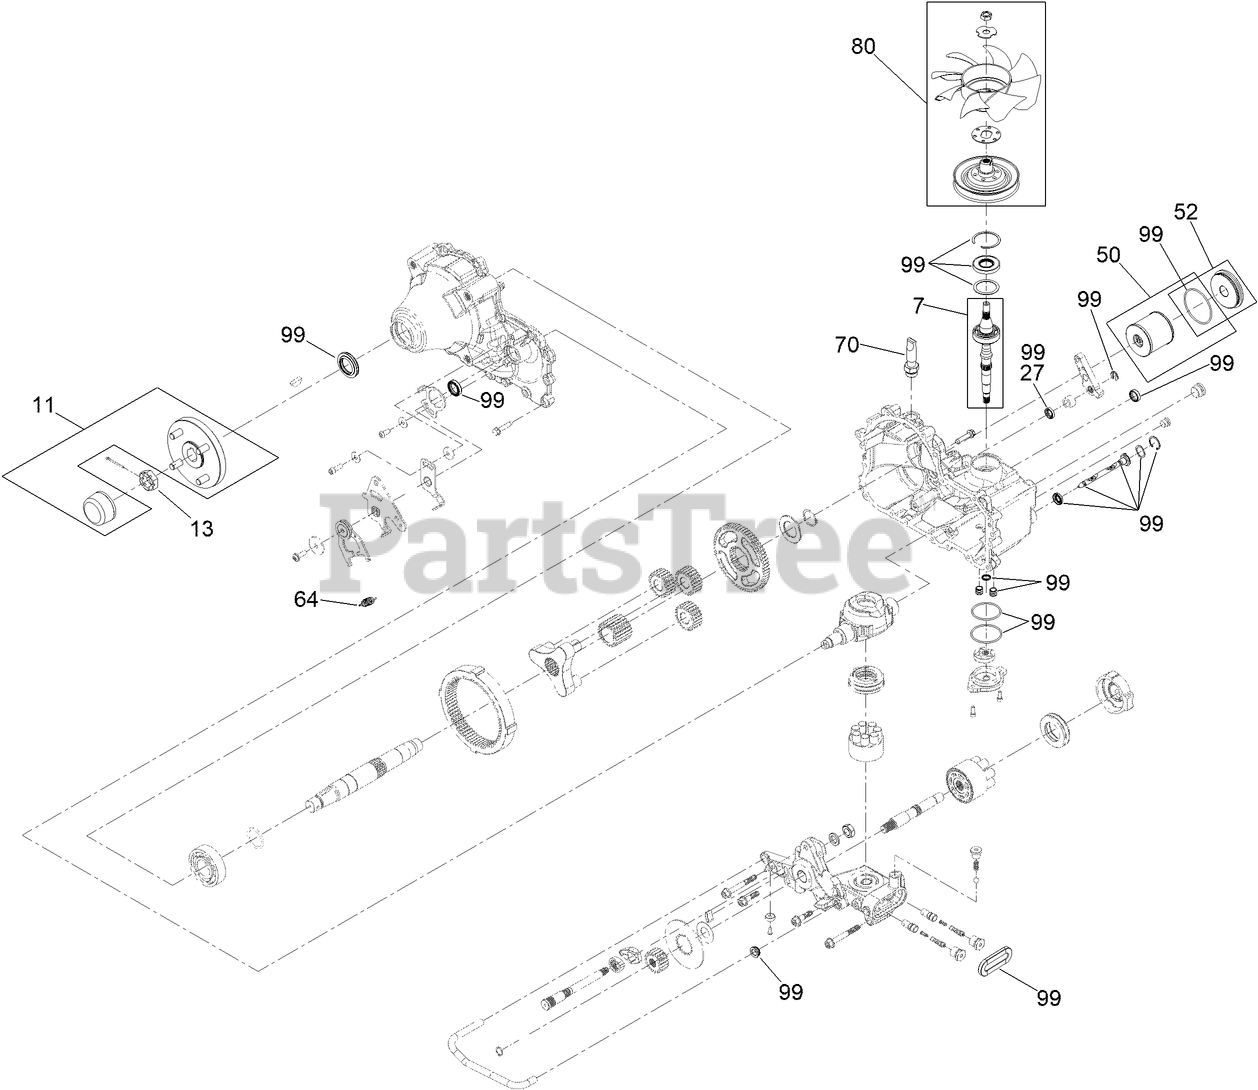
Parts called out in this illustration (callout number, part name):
7	KIT, INPUT SHAFT
11	HUB-4 BOLT
13	NUT, SLOTTED
27	SEAL, LIP-BRAKE
50	KIT, FILTER
52	KIT, FILTER PLUG
64	SPRING-EXTENSION
70	FITTING-5/8 BEADED, 7/8 SAE
80	KIT, FAN AND PULLEY
99	KIT-OVERHAUL SEAL
